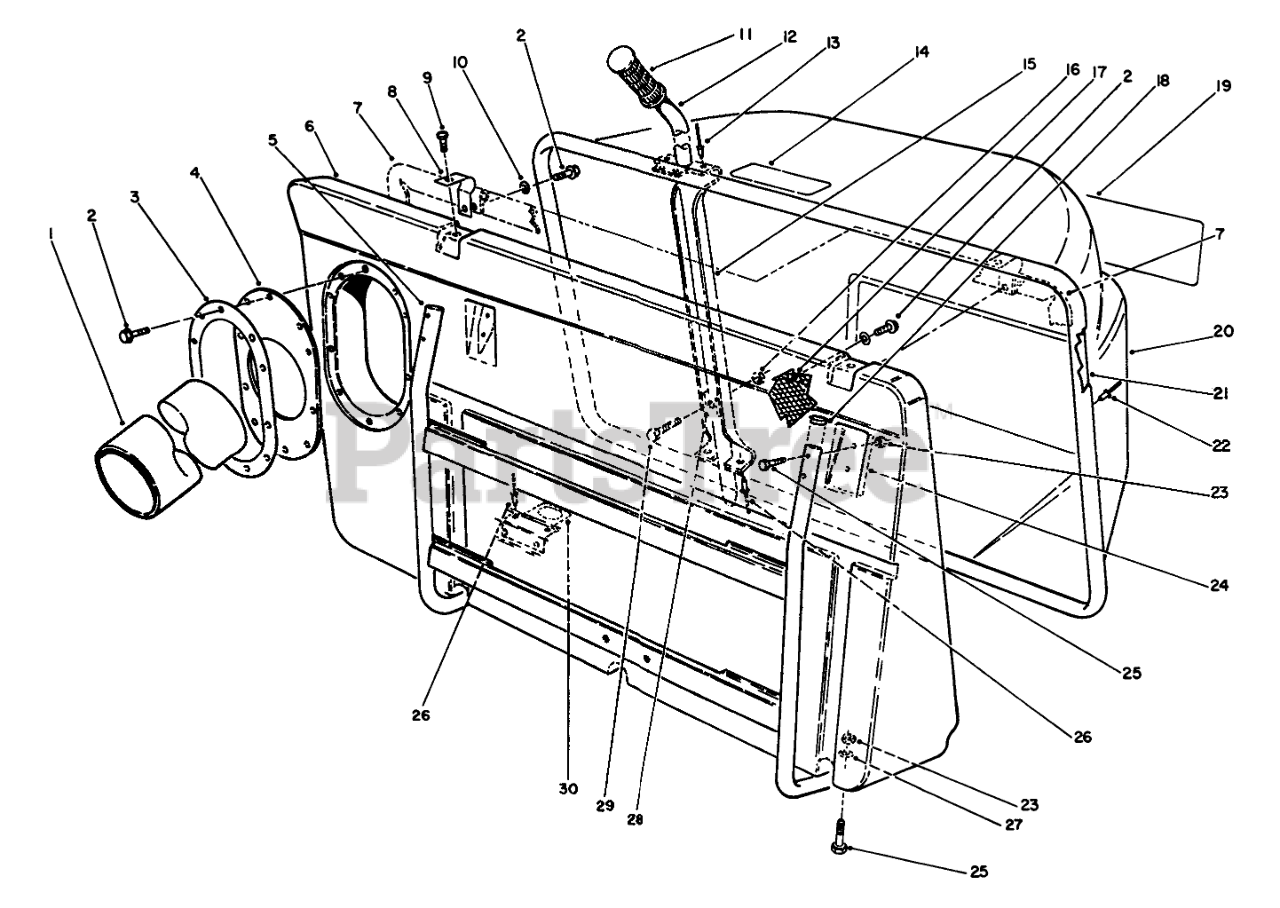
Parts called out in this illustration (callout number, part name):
1	Duct (Ref.)
2	Screw-Self Tapping
3	RING-RETAINING
4	Seal (Ref.)
5	Frame
6	BAG-FRONT
7	SEAL-BAG
8	Bracket-Hinge
9	Screw
10	WASHER-FLAT
11	GRIP-HANDLE
12	HANDLE-DUMP
13	Rivet-Pop
14	Decal Warning
15	Channel-Dump Handle
16	NUT-LOCK, NI
17	Screen Bag
19	DECAL - TORO
20	BASKET-GRASS
21	Frame-Grass Basket
22	NUT-LOCK
23	NUT-LOCK, NI
24	Plate-Backup
25	SCREW-HH
26	RIVET-BLIND
27	Washer
28	GUIDE-HANDLE, DUMP
29	SCREW-HH
30	Latch
